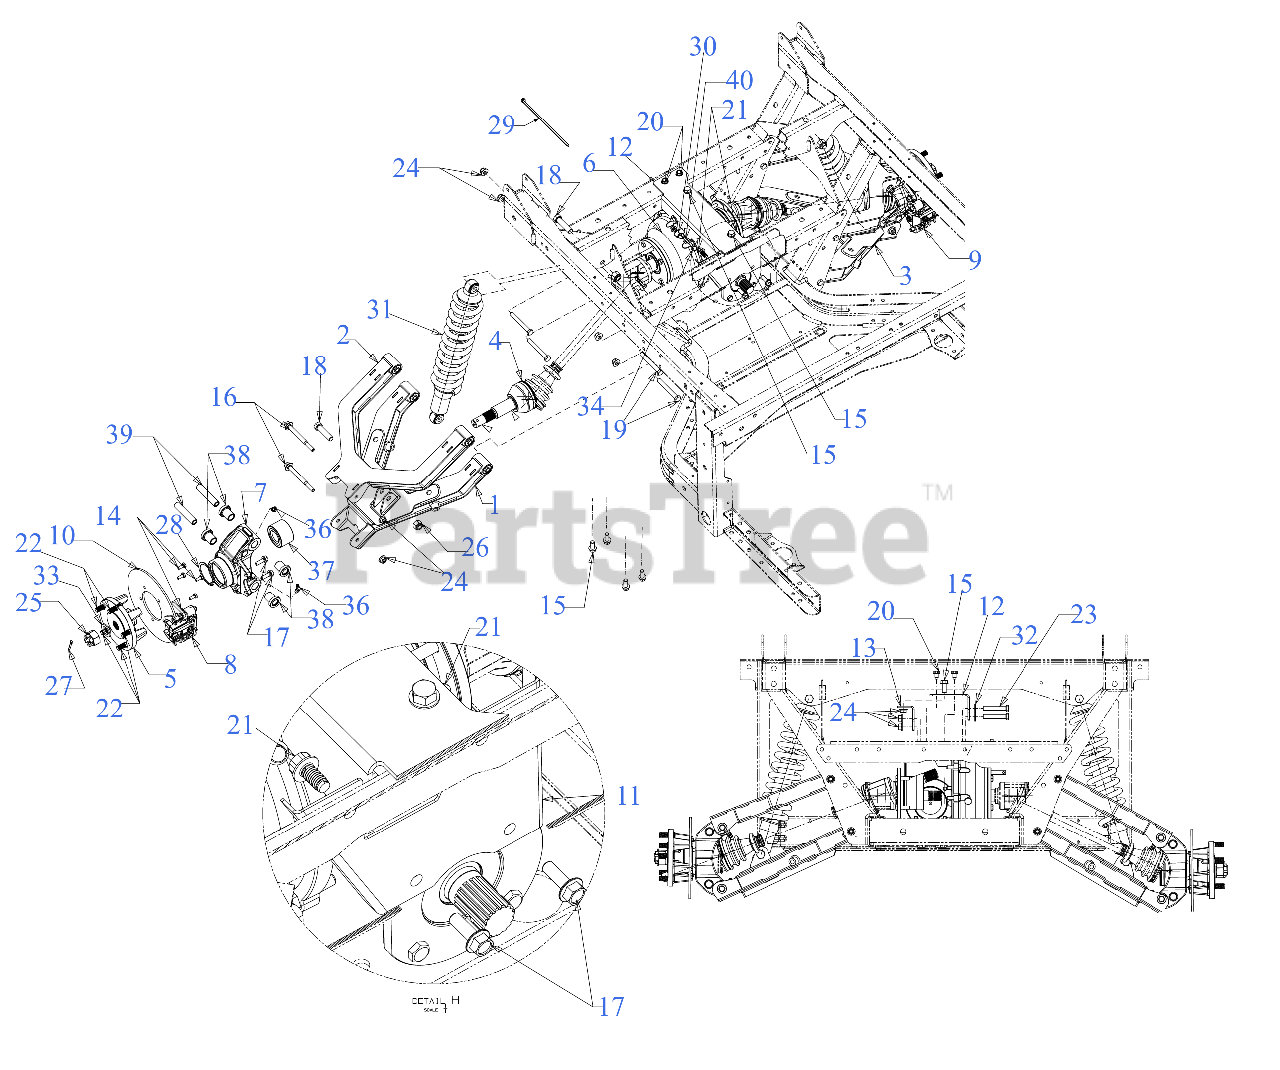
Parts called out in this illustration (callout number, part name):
1	CONTROL ASSEMBLY-LOWERR/(RH)
2	CONTROL ASSEMBLY-UPPER RR
3	LOWER CONTROL ASSEMBLY (LH)
4	AXLE:ASSEMBLY:CV JOINT:
5	WHEEL HUB ASSEMBLY
6	UV REAR DRIVE KIT
7	4X4 REAR HOUSING
8	CALIPERBRAKE ASSEMBLY- FRONT (RH)
9	CALIPERBRAKE ASSEMBLY- FRONT (LH)
10	BRAKE DISC 8.00 x .188
13	REAR DIFFERENTIAL BRACKET
14	SCREW 1/4-20 x .62 SPEC GR5
15	SCREW 3/8-16 x .875 GR5
16	SCREW 3/8-16 x 4.00 GR5
17	SCREW M8 x 1.25 x 25MM GR8.8
18	SCREW 1/2-13 x 2 GR5
19	SCREW 3/8-16 x 3 GR8
20	SCREW 5/16-18 x .500
21	SCREW 3/8-16 x 3/4
22	STUD 7/16-14 x 1.6
23	SCREW 3/8-16 x 2.25 GR5
25	SLOTTED NUT22X1.5
26	HEX LOCK NUT NYLON
27	COTTER PIN-5/32 DIA
28	RETAINING RING
29	7" CABLE TIE
30	HOSE CLAMP
31	REAR SHOCK ABSORBER
32	FLAT WASHER .385X.870X.090
33	THRUST WASHER .88X1.38X.125
36	45 DEGREE LUBE FITTING 1/4-28 TAPER
37	DOUBLE ROW BEARING
38	FLANGE BEARING .625 ID
40	FUEL HOSE LOW PERMEATION 22"
